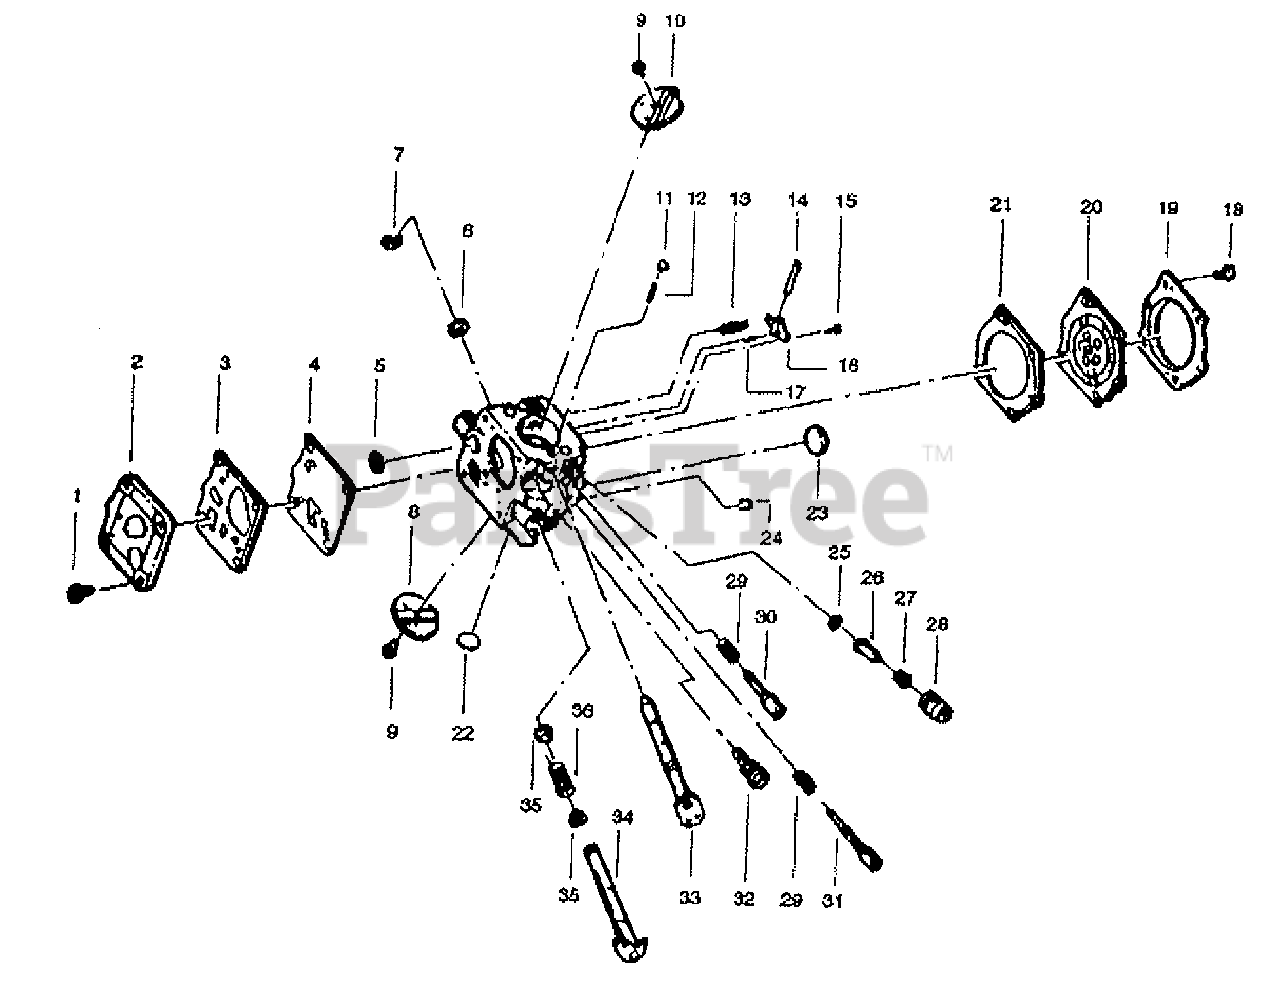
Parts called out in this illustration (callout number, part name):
3	Gasket Set
4	Gasket Set
5	Repair Kit
8	Throttle Valve
10	Choke Shutter
20	Gasket Set
21	Gasket Set
22	Repair Kit
23	Repair Kit
24	Repair Kit
26	Gasket Set
28	Plug Cover
29	Screw
30	Hi Speed Needle
31	Idle Needle
33	Shaft Ass'y - Choke
34	Shaft Ass'y - Throttle
